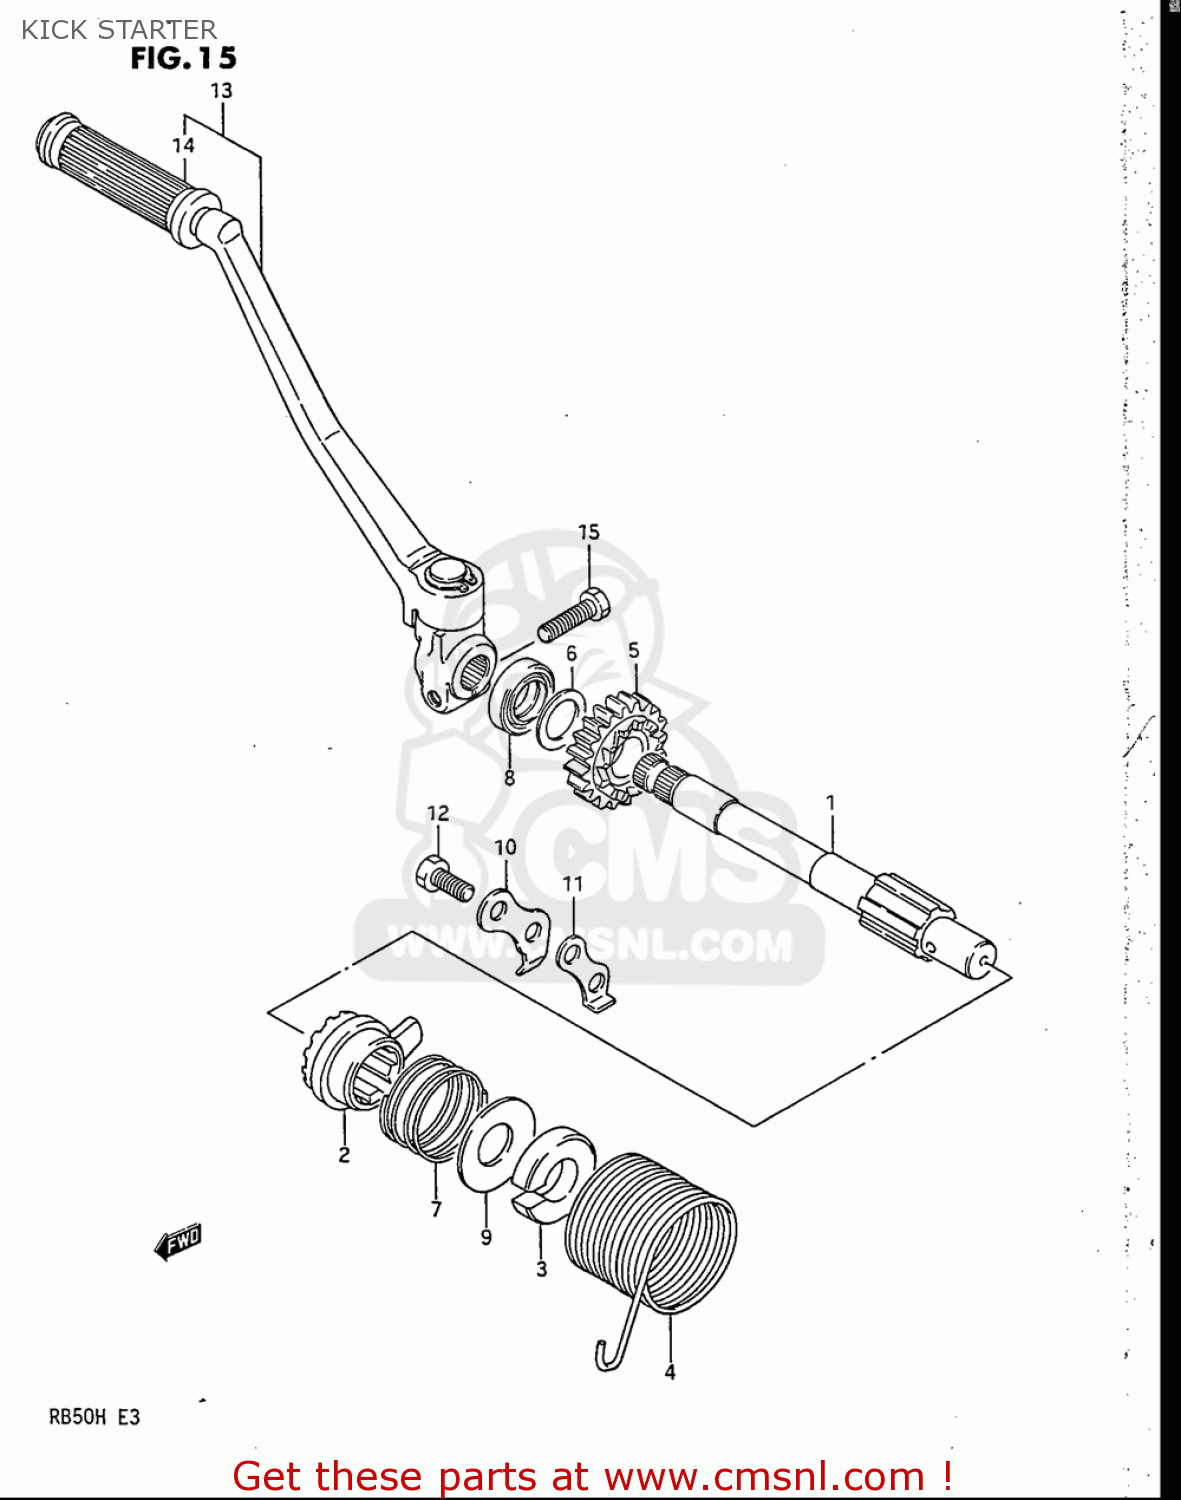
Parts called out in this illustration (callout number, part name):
2	STARTER,KICK
5	GEAR,KICK STARTER DRIVE (
6	SHIM(14X22X1)
7	SPRING
8	SEAL,OIL(14X24X6)
9	WASHER
12	BOLT
13	LEVER ASSY,KICK STARTER
14	RUBBER,KICK STARTER PEDAL
15	BOLT
